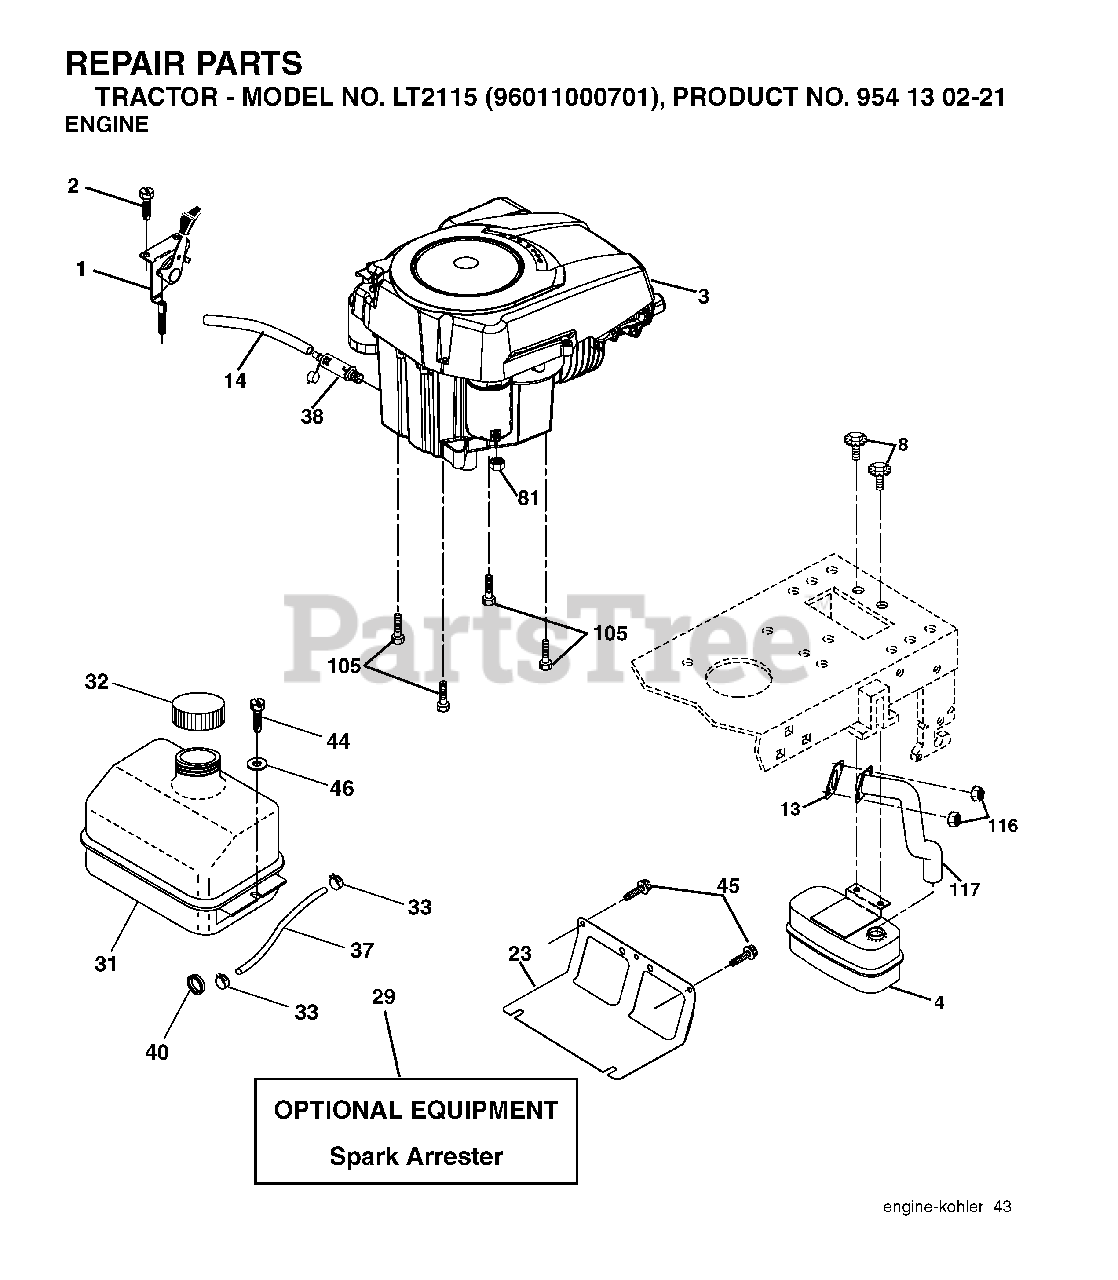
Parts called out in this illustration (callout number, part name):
1	CONTROL.THROTTLE.LT/YT
2	SCREW
4	MUFFLER.SINGLE.CYL.KOHL/B&S
8	BOLT, 5/16-18 X 1 3/4
13	GASKET ENGINE
14	TUBE, DRAIN OIL ASM.
23	SHEILD.BROWNING.DBR.GUARD
29	ARRESTER SPARK (OPTIONAL)
31	TANK FUEL FRONT
32	FUEL CAP
33	HOSE CLAMP
37	LINE.FUEL.20
38	PLUG DRAIN OIL EASY
40	GROMMET T
44	SCREW HEXWSHR 1/4-20X3/4
45	SCREW, 3/8-16X3/4
81	NUT
105	SCREW 3/8-16X1
116	NUT.HEX.FLANGE.TOPLOCK
117	TUBE EXHAUST
